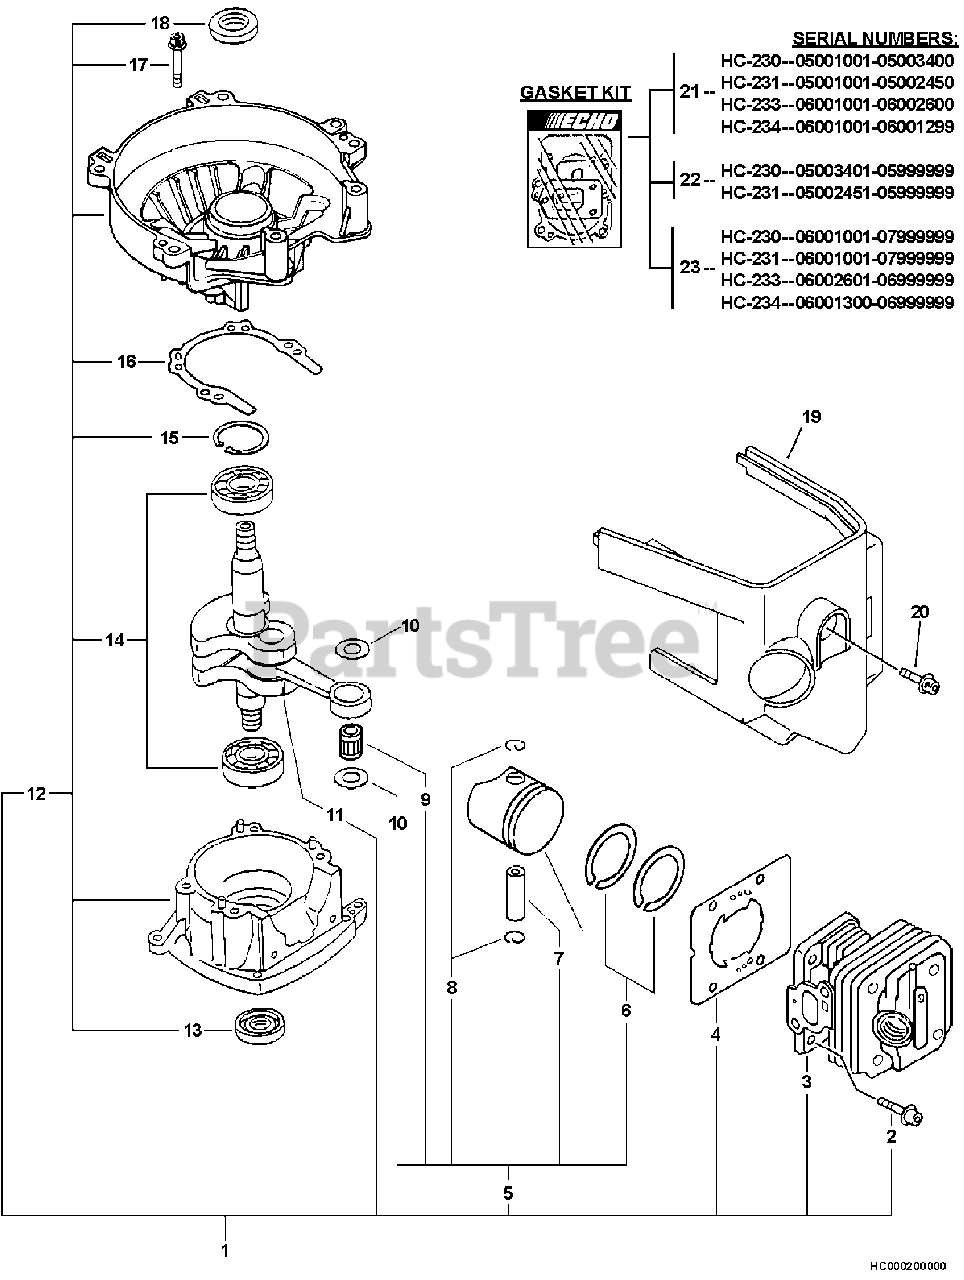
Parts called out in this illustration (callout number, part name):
1	SHORT BLOCK -- SB1063
2	SCREW - 5X22
3	CYLINDER
4	GASKET, CYLINDER
5	PISTON KIT
6	RING, PISTON
7	PIN, PISTON
8	RING, RETAINING
9	BEARING, NEEDLE - 8
10	SPACER, PISTON
11	CRANKSHAFT ASSY
12	CRANKCASE KIT
13	SEAL, OIL
14	BEARING, BALL - 6001C3
15	RING, RETAINING - 28
16	GASKET, CRANKCASE
17	SCREW - 5X25
18	SEAL, OIL - 12
19	COVER, ENGINE
20	SCREW - 5X16
21	GASKET KIT
22	GASKET KIT
23	GASKET KIT
